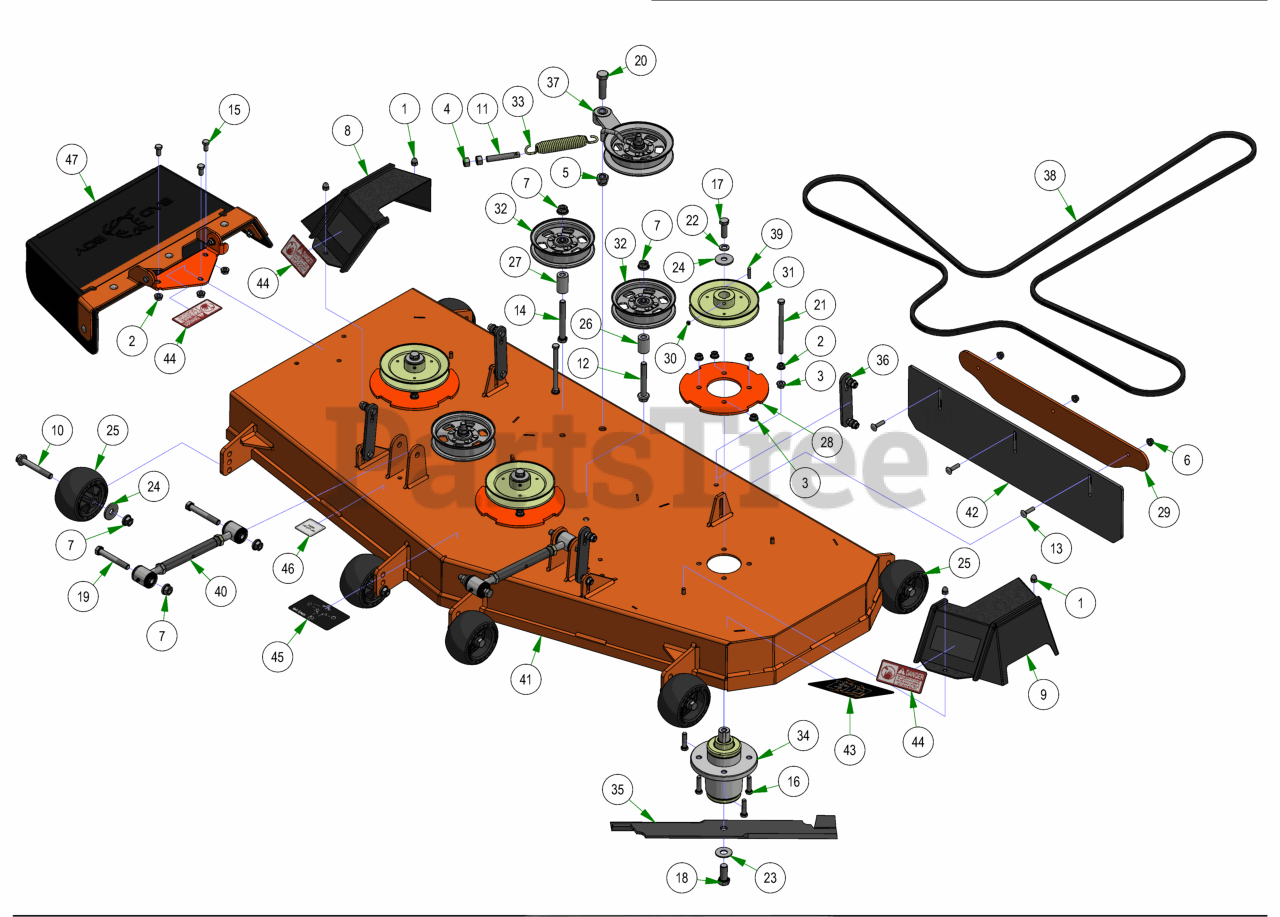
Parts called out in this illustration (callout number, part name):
1	5/16-18 ACORN NUT HIGH-CROWN ZC
2	3/8-16 HEX SERRATED FLANGE NUT HARD/ZINC
3	3/8-16 NYLON INSERT FLANGE LOCKNUT (GR.F) ZINC
4	1/2-13 HEX NUT ZINC
5	5/8-11 NYLON INSERT LOCKNUT ZINC
6	5/16-18 NYLON INSERT FLANGE LOCKNUT ZINC
7	1/2-13 NYLON INSERT FLANGE LOCKNUT ZINC
8	2021 Maverick 54”/60” RH Pulley Cover
9	2021 Maverick 54”/60” LH Pulley Cover
10	1/2-13 X 90MM HEX FLANGE BOLT W/SHOULDER (GR.8) ZINC
11	All Thread
12	1/2-13 X 3-1/2 HEX FLANGE BOLT (GR.8) ZINC
13	5/16-18 X 1-1/4 CARRIAGE BOLT ZINC
14	1/2-13 X 4 HEX CAP SCREW (GR.8) ZINC YELLOW
15	3/8-16 X 3/4 HEX CAP SCREW (GR.5) ZINC
16	3/8-16 X 1-1/2 HEX CAP SCREW (GR.5) ZINC
17	1/2-20 X 1-1/2 HEX CAP SCREW (GR.5) ZINC
18	5/8-18 X 1-1/2 HEX CAP SCREW (GR.8) ZINC YELLOW
19	1/2-13 X 3-1/2 HEX CAP SCREW (GR.5) ZINC
20	5/8-11 X 2-1/4 HEX CAP SCREW (GR.5) ZINC
21	3/8-16 X 5-1/2 HEX CAP SCREW (GR.5) ZINC
22	1/2 SPLIT LOCKWASHER (GR.8) ZINC/YELLOW
23	5/8 USS FLAT WASHER (1-3/4" OD) GR.8 ZINC YELLOW
24	1/2 BELLEVILLE WASHER (1-5/8 OD X .140 THK) ZINC
25	Deck Wheel
26	.502 ID X .750 OD X 1.500 Long Spacer
27	1 3/4" Pulley Spacer
28	Deck Spindle Support Plate
29	2023 4" & 5" Stripping Kit Plate
30	5/16-24 X 1/4 SOCKET SET SCREW (CUP PT) PLAIN
31	6 1/4" Drive Pulley
32	5-3/4 Idler Pulley
33	Deck Idler Spring
34	OUTLAW SPINDLE ASSEMBLY
35	60" High Lift Fusion Blade
36	Deck Hanger Assembly
37	Maverick HD & Down Deck Idler Assembly
39	1/4 X 1 SQ MACHINERY KEY 1018 STL PLN
40	2018 Maverick Turnbuckle (Top Link)
41	2025 60" x 5" Deck
42	2023 ZT Stripping Kit Rubber
43	60" Grip Deck Decal
44	Danger Decal-Spindle/Discharge
45	Deck Belt Route Decal
46	Deck Impact Patent Decal 9591803
47	Discharge Chute Assembly
